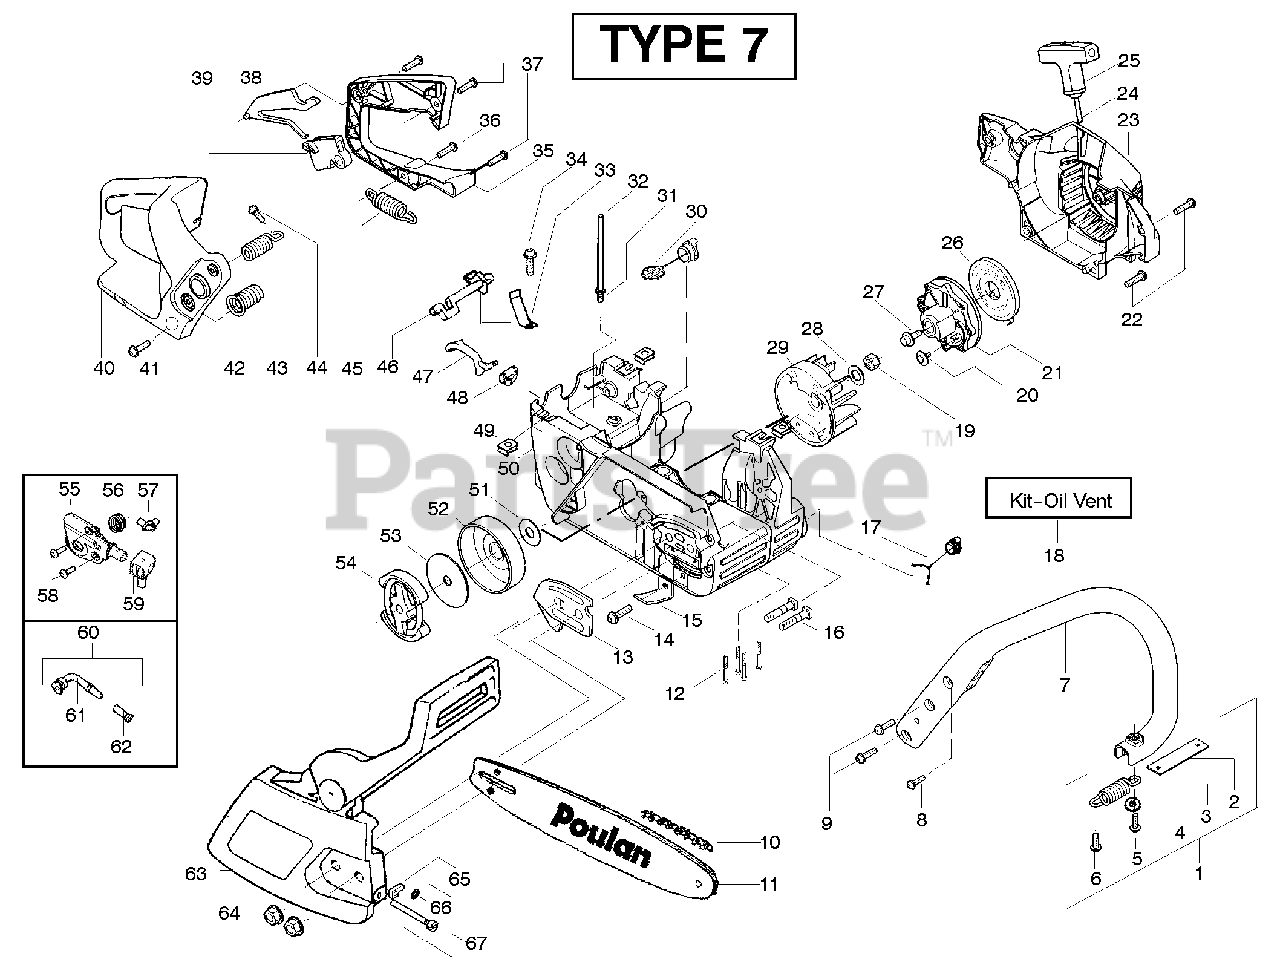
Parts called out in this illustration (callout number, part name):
1	Assy.-Isolator
2	Limiter Strap
3	Spring-Isolator
4	Washer
7	Front Handle
10	Chain-18"
13	Plate-Bar Mount.
15	Chain Catcher
17	Assy-Oil Cap
21	Starter Pulley
25	Handle-Starter
26	Spring-Recoil
28	Washer-Flywheel
29	Assy-Flywheel
30	Assy-Fuel Cap
31	Fitting-fuel line
32	Kit-Fuel line (large)
33	Spring-Switch
35	Cover-Rear Handle
38	Throttle Lockout
39	Trigger-Throttle
41	Screw
42	Assy Isolator-lower
43	Kit-Isolator (Upper)
45	Spring-Isolator
50	Assy-Chassis fuel lines and caps
51	Washer-Thrust
52	Assy.-Clutch Drum w/bearing
53	Washer-Clutch
55	Kit-Oil Pump
56	Gear-Worm Spring
57	Elbow-Oil Pickup
60	Assy-Oil Pick-up
61	Pick-up Oiler
63	Assy.-Chain Brake
64	Nut-Bar Mounting
65	Pin-Bar Adjust
67	Kit-Bar Adjusting
